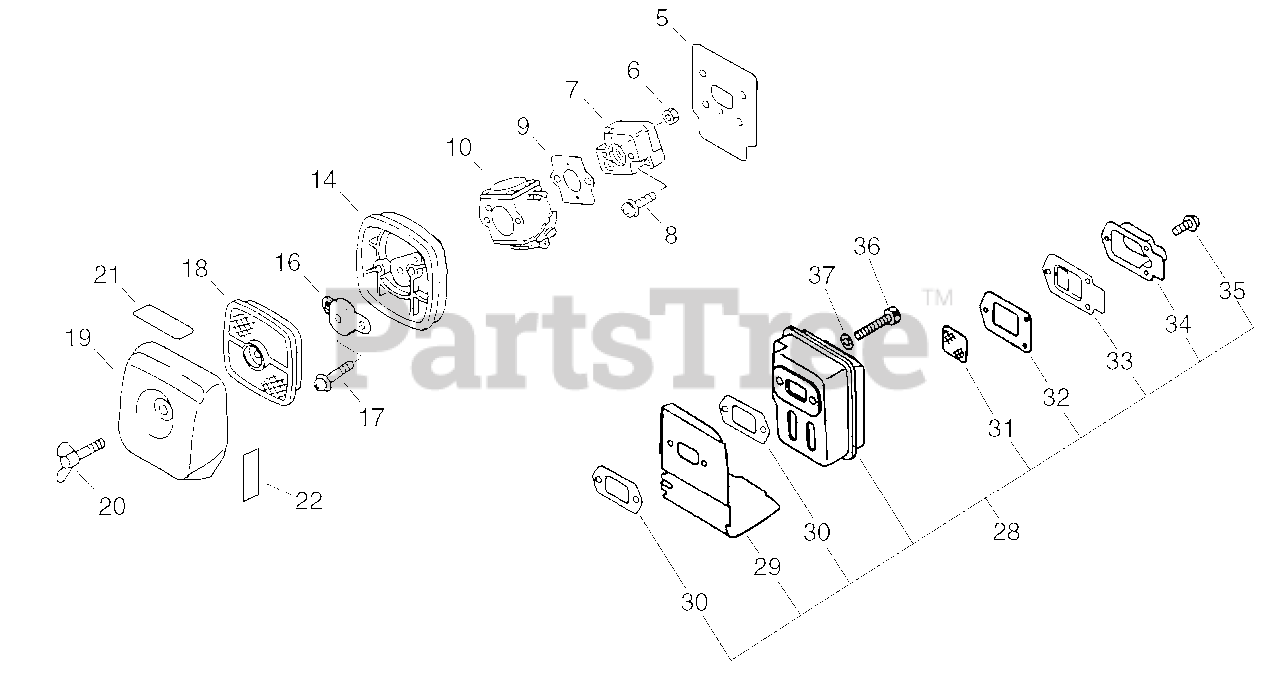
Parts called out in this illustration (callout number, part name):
5	HEAT SHIELD, INTAKE
6	NUT M5
7	INSULATOR, INTAKE
8	SCREW 5×20
9	GASKET, CARBURETOR
10	CARBURETOR
14	CASE ASSY, AIR FILTER
16	PLATE, PREVENT
17	SCREW 5×65
18	FILTER, AIR - DOUBLE LAYER
19	COVER, AIR FILTER - BLACK
20	BOLT, WING 5×20
21	LABEL, METERING
22	LABEL, CHOKE
28	MUFFLER ASSY
29	HEAT SHIELD, EXHAUST
30	GASKET, EXHAUST
31	SCREEN, SPARK ARRESTER
32	GASKET, EXHAUST
33	GUIDE, EXHAUST
34	OUTLET, EXHAUST
35	SCREW 4×10
36	BOLT 5×55
37	WASHER, FLAT 5.5×10×0.8
